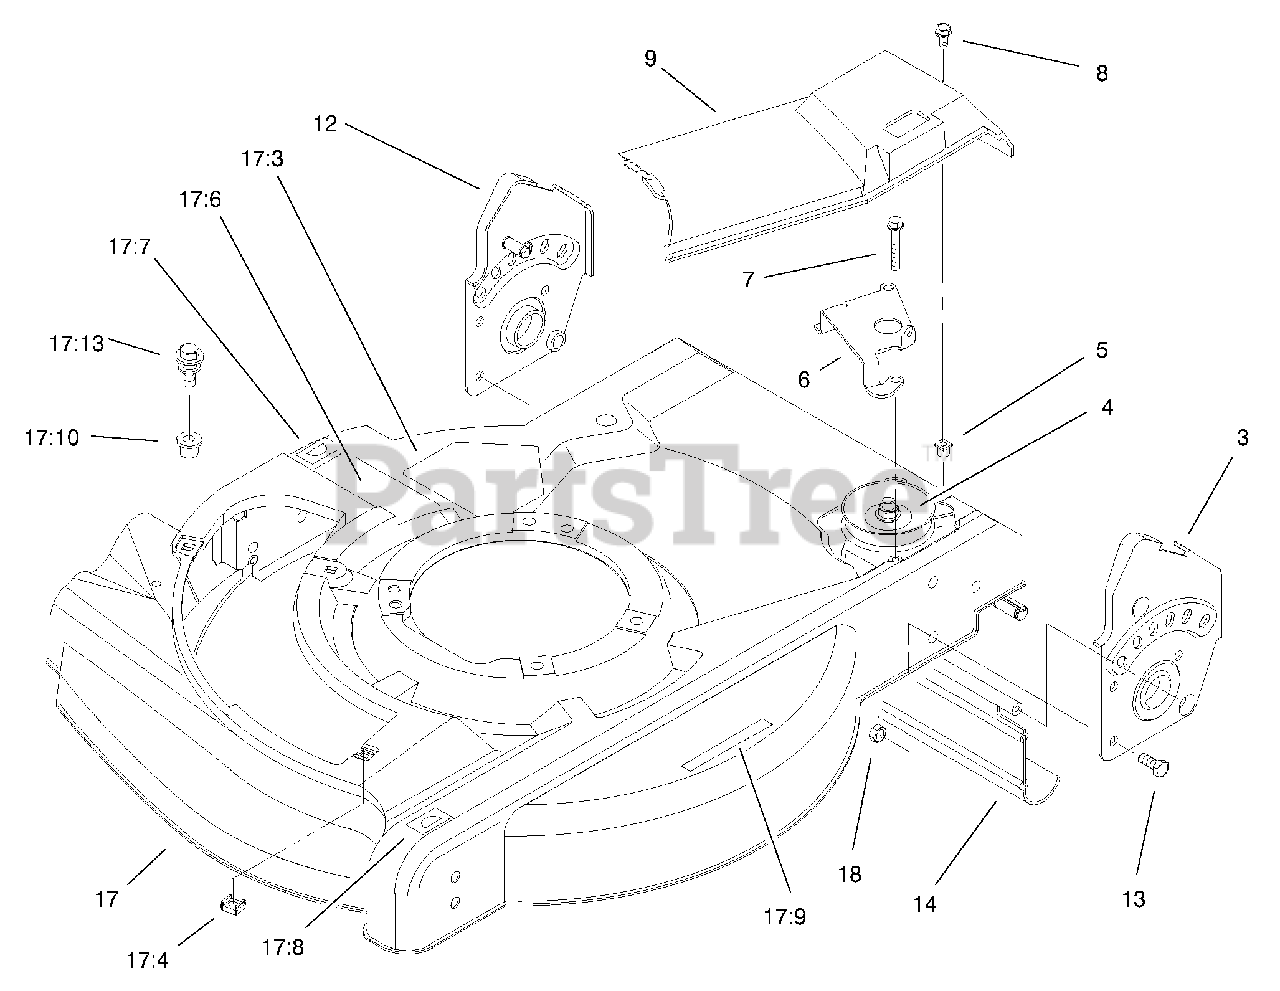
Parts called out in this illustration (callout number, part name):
3	LH Handle Bracket ASM
4	Gear Case ASM
5	Grommet
6	Guide-Transmission
7	Screw-HWHTF
9	Cover-Drive
12	RH Handle Bracket ASM
13	Screw-HH
14	Shield-Trailing
17	Deck ASM
17:3	Decal-Danger
17:4	Nut-Cage
17:6	Decal-Warning
17:7	Decal-HOC, RH
17:8	Decal-HOC, LH
17:9	Decal-Warning
17:10	Grommet-Plastic
17:13	Screw-Sems
18	Nut-Lock, NI
